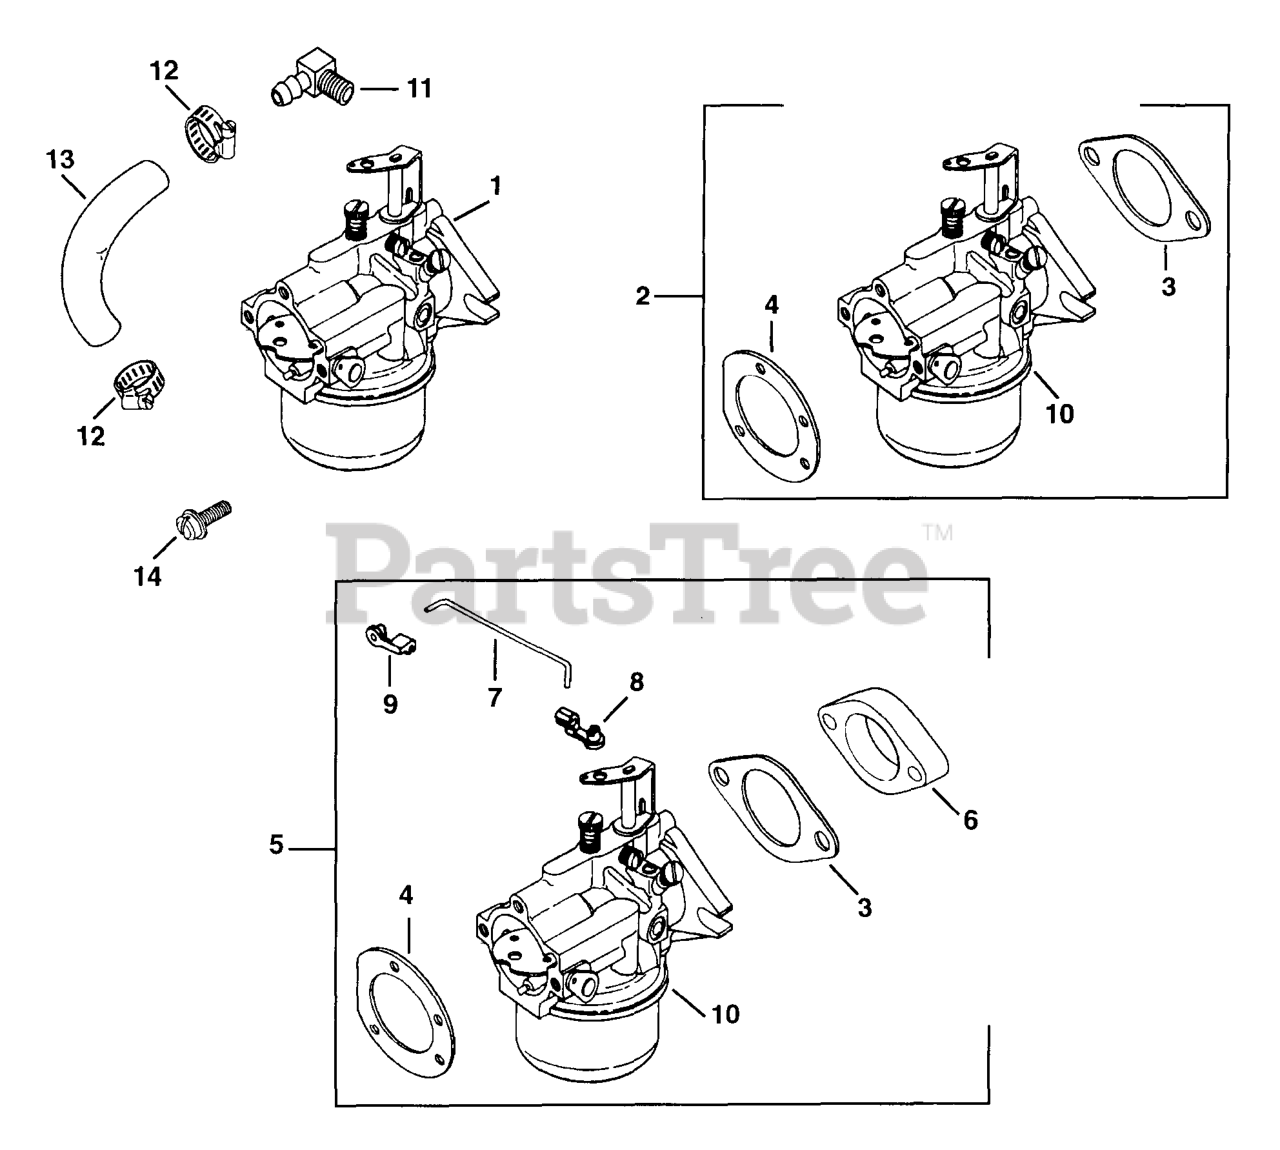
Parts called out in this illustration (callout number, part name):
2	KIT, CARBURETOR
3	GASKET/SPACER, CARBURETOR
4	GASKET, AIR CLEANER
10	CARBURETOR ASSEMBLY - DISCONTINUED
11	CONNECTOR, 90 DEG. HOSE
12	CLAMP, HOSE 1/2" USE 25 237 14-S
13	LINE - DISCONTINUED
13	LINE, FLEXIBLE FUEL - DISCONTINUED
14	SCREW, SLT HD 5/16-18X1" - DISCONTINUED
